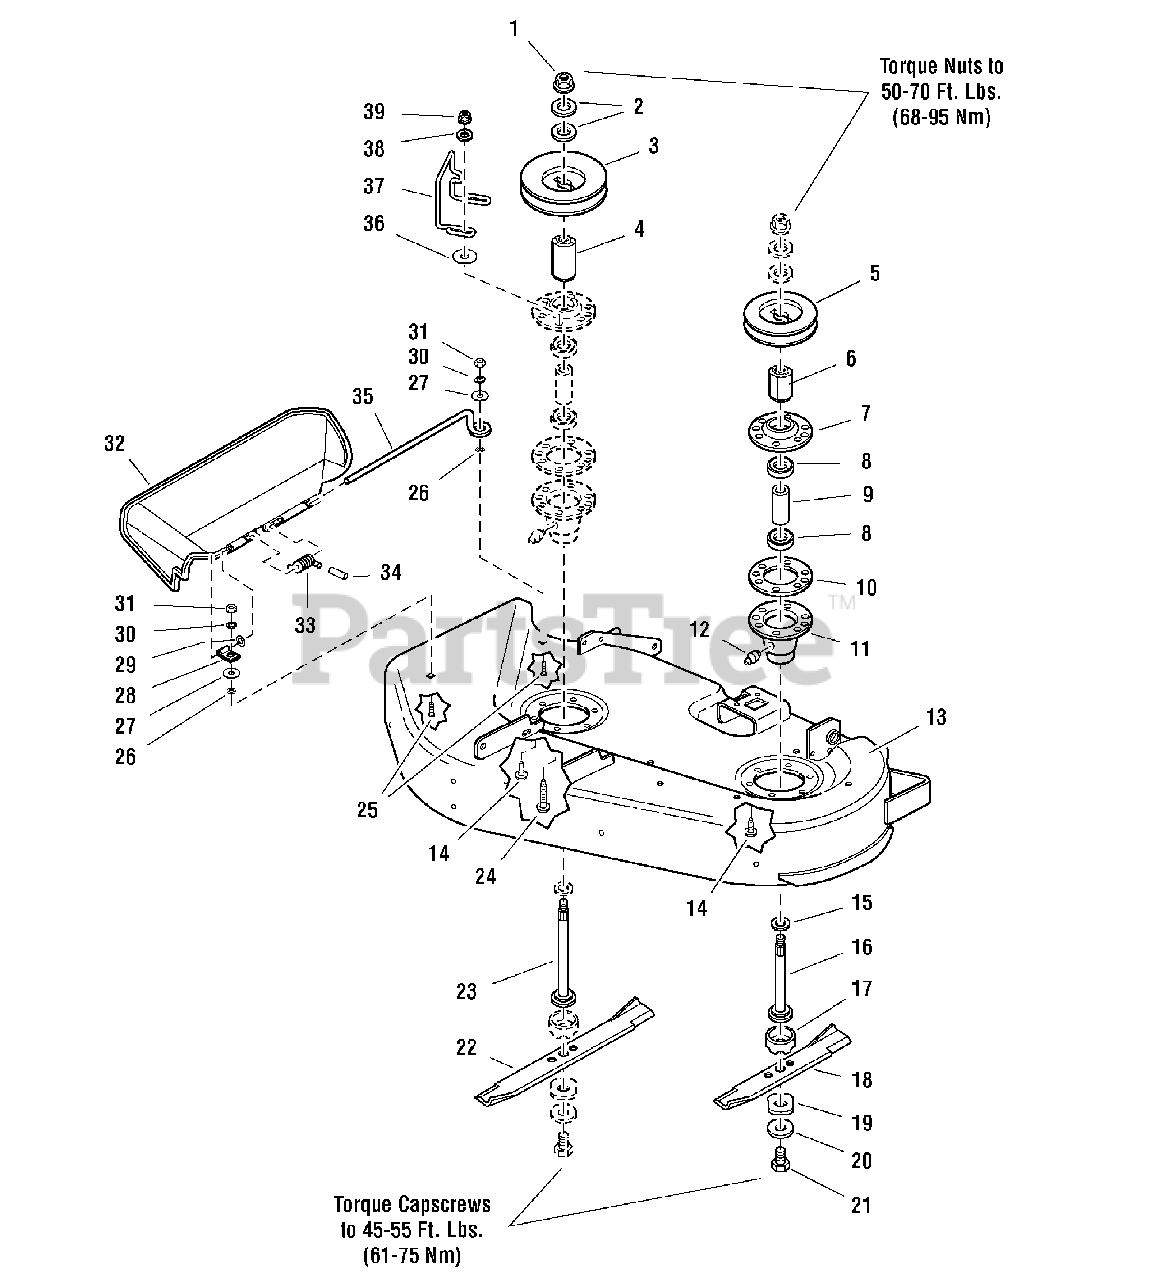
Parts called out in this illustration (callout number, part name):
1	NUT, Hex Flange, 9/16-18
2	WASHER, Belleville
7	COVER, Arbor Housing
10	GASKET, Foam
11	HOUSING, Arbor, Bottom (Includes Ref. No. 12)
12	FITTING, Lube
13	DECK SHELL W/ DECALS, 34" Pacer
14	CAPSCREW, Hex Washer Head, Taptite, 5/16-18 x 3/4, Black
16	SHAFT, Arbor
17	SHIELD, Grass
18	BLADE, Mower, 14.42
19	WASHER, Hex, Special
20	WASHER, Spring
21	CAPSCREW, Hex Head, 7/16-14 x 1-1/4, Black
22	BLADE, Mower, 19.90
23	SHAFT, Arbor
24	CAPSCREW, Hex Washer Head, Taptite, 5/16-18 x 1-1/2, Black
25	CARRIAGE BOLT, 1/4-20 x 7/8, Black
26	NUT, Push, 1/4, Black
27	WASHER, 1/4, Black
29	WASHER, 5/16, Black
30	LOCKWASHER, 1/4, Black
31	NUT, Hex, 1/4-20, Black
32	DEFLECTOR, Plastic
33	SPRING, Torsion
34	CAP, Spring End
35	ROD, Deflector, Front
36	WASHER, 5/16, Black
38	WASHER, 5/16, Black
39	NUT, Hex Flange, 5/16-18
